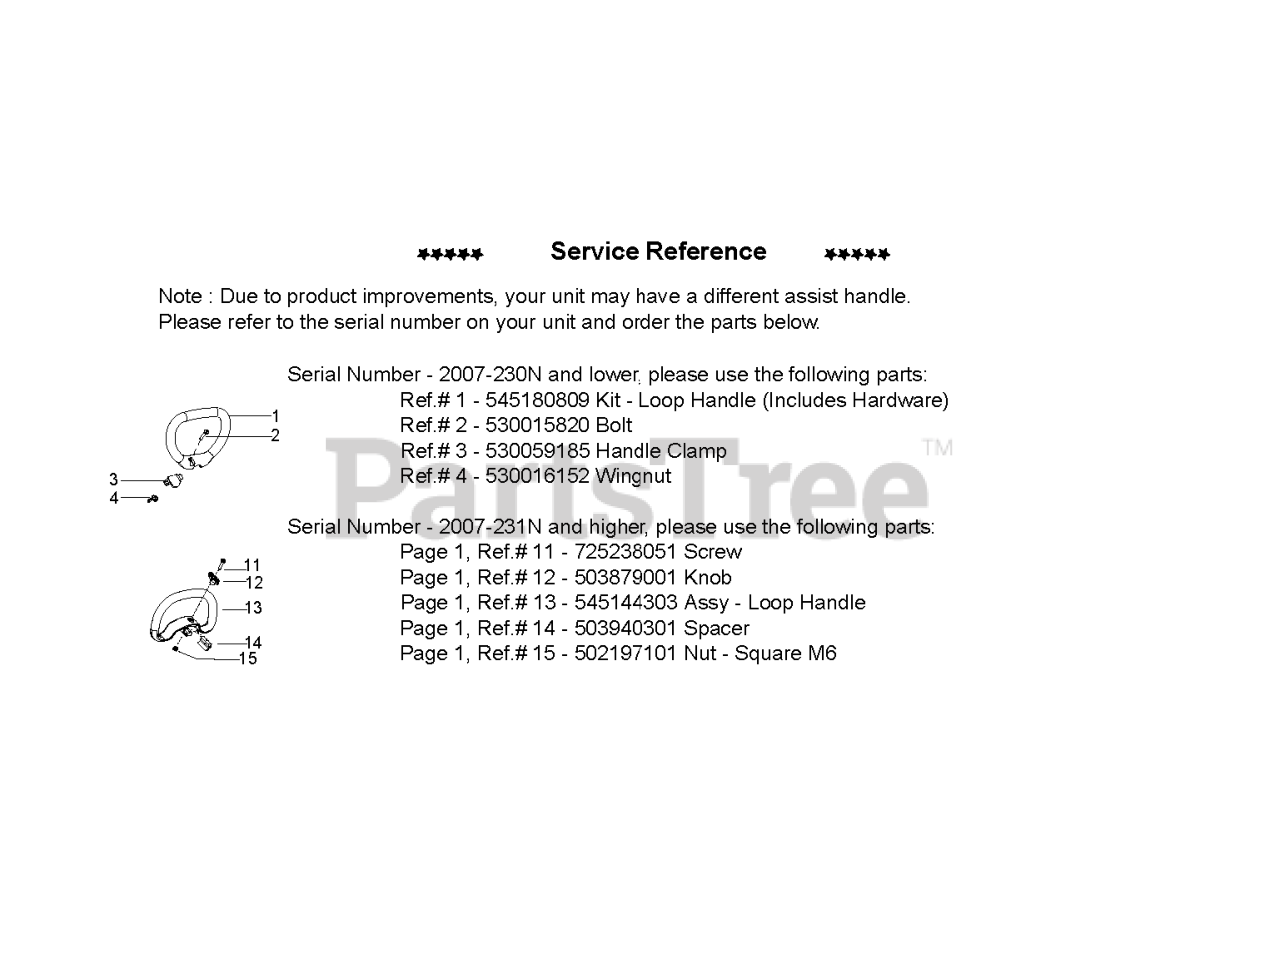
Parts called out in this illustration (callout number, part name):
1	ASSY LOOP HANDLE
2	BOLT, TYPE 2
3	CLAMP ASSIST HANDLE
4	WINGNUT, TYPE 2
11	SCREW M6X50
13	ASSY LOOP HANDLE
14	SPACER PLASTIC
